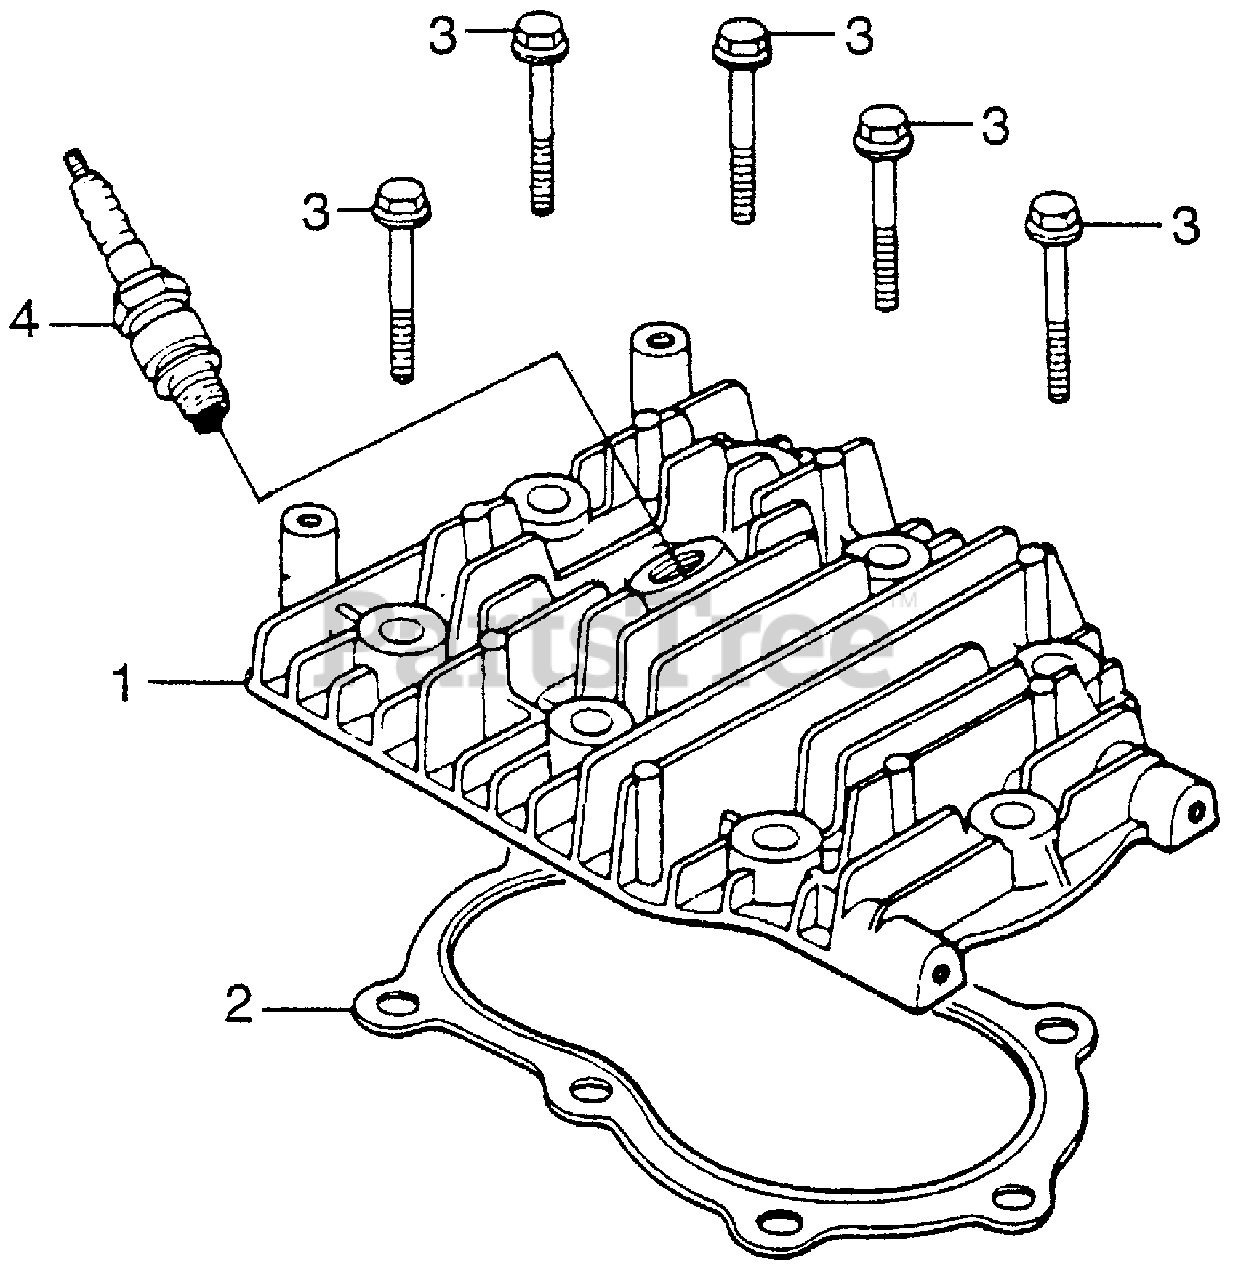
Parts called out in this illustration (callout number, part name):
1	CYLINDER HEAD
2	GASKET, CYLINDER HEAD
3	BOLT, FLANGE (8X40)
4	SPARK PLUG (B6HS) (NGK)
